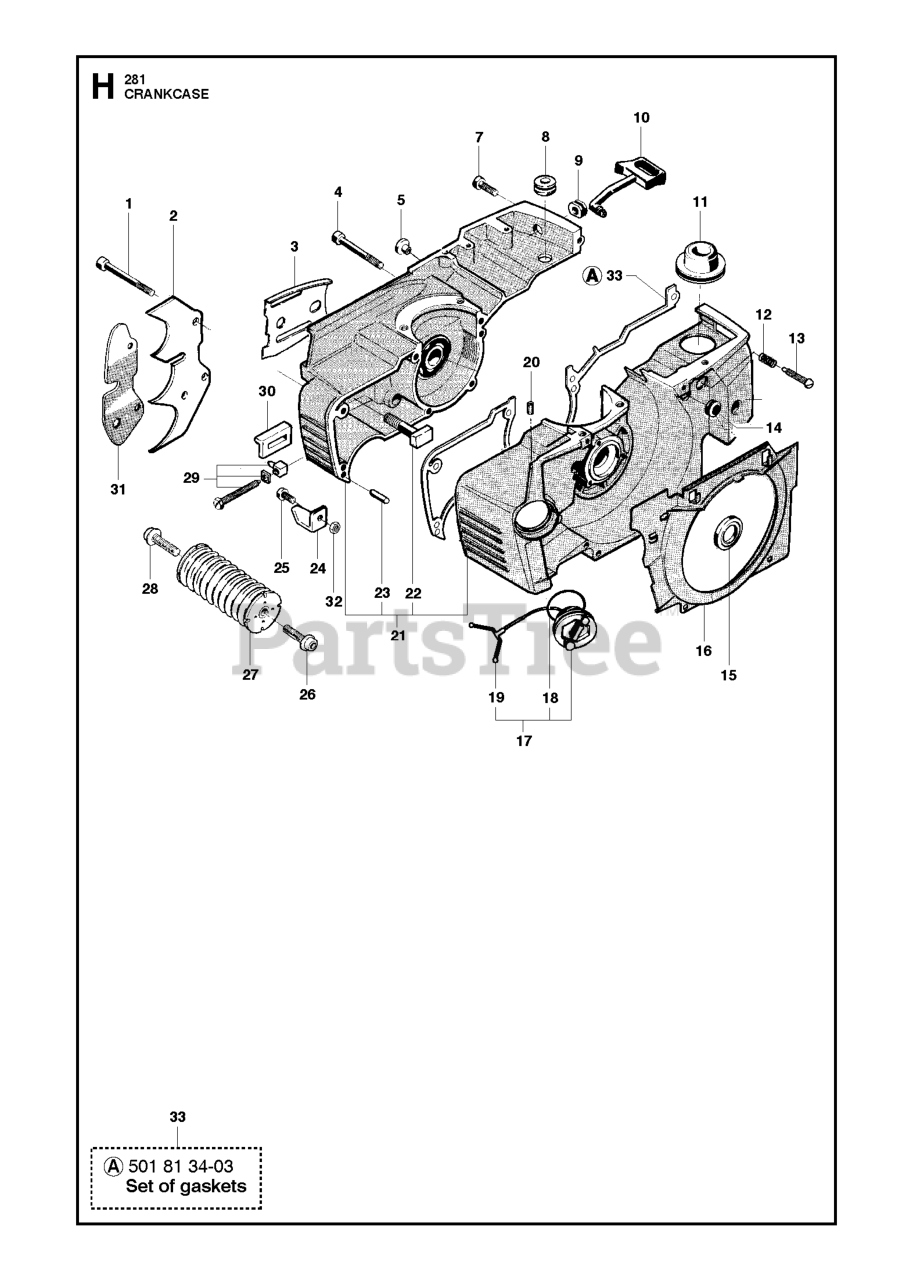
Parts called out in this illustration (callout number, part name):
1	SCREW MC6S 5X55
2	FELLING DOG
3	PROTECTION PLATE
4	SCREW MC6S 5X35
7	SCREW MC6S 5X16
10	CHOKE CONTROL
15	SEALING RING
16	AIR CONDUCTOR
20	OIL TANK VENT
21	CRANK CASE W/BEARING
23	GUIDE BUSHING
24	CHAIN CATCHER
25	SCREW MC6S 5X16
29	CHAIN TENSIONER
30	CHAIN GUIDE
31	FELLING DOG
33	GASKET KIT
